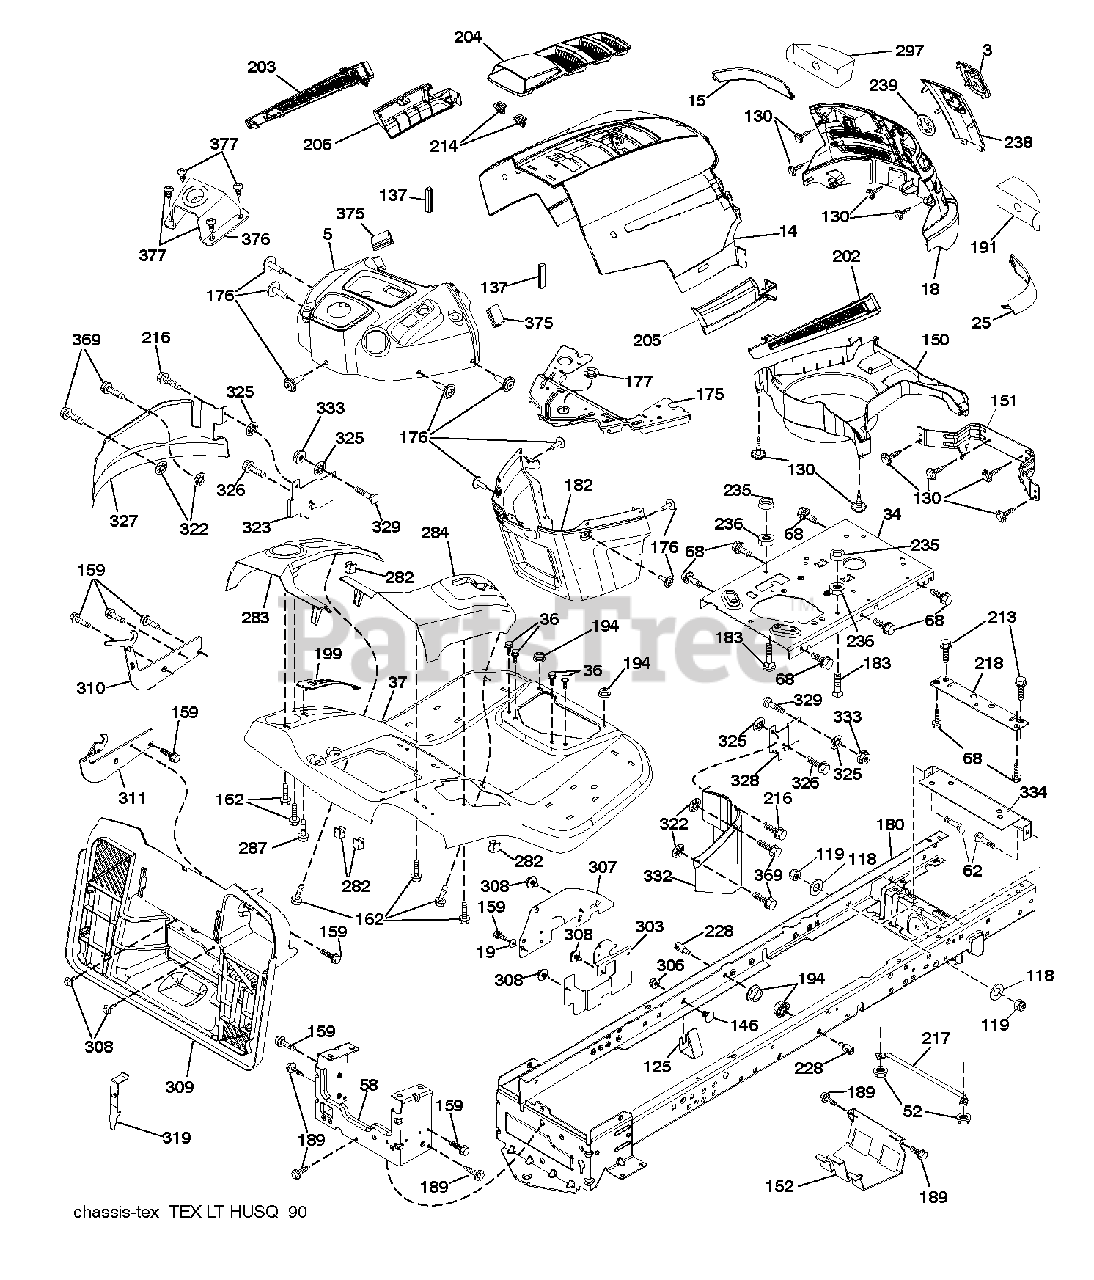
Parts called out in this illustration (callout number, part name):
3	LOGO.HUSQ.GT.LT.CROWN.H
5	DASH.UPPER.HUSQ LT CABLE.CLUTC
14	HOOD.HUSQVARNA.LT.ORANGE
15	LENS.HUSQVARNA LT.RH
18	GRILLE.SVC.HUSQVARNA.GREY
19	WASHER
25	LENS.HUSQVARNA LT.RH
34	PLATE.ENGINE.10GA.CRD.GENII
36	SCREW 5/16"
52	LOCKNUT
58	DRAWBAR UPPER 2PC SMALL FENDER
62	BOLT D
68	SCREW LT
118	WASHER
125	CLIP.FUEL.LINE
130	SCREW.#10 X 0.750.BOS
137	BUMPER DASH
146	BOLT.RDHD.SHT.SQNK.3/8-16X5/8
151	BRACKET PIVOT
152	SHIELD.BROWNING.W/TEX
159	SCREW, 3/8-16X3/4
162	SCREW.HI-LO.CONSOLE
175	CROSSMEMBER
176	SCREW.#10-24X5/8.RN.QU
177	BUSHING STEERING
180	CHASSIS.WLDMNT.14GA.2PC.18".TI
182	DASH.LOWER.PREDATOR LT
183	BOLT.5/16-18X1-1/4 FULL THD
189	SCREW
191	INSERT.REFLECTIVE.RH.
194	NUT LOCK HEX FLANGE 5/16-18
199	PLATE DECK LIFT
202	VENT.SIDE.HUSQVARNA.LT.RT
203	VENT.SIDE.HUSQVARNA.LT.LFT
204	SUBASM.TOP.VENT.HUSQ.LT
205	SKIRT.SIDE.HUSQVARNA.LT.RT
206	SKIRT.SIDE.HUSQVARNA.LT.LEFT
213	BOLT
214	CLIP.RETAINER.TINNER.
216	SCREW, 5/16-18 X 1/2
217	ROD.PIVOT.HOOD
218	X-PIECE.HOOD.STOP.NON/
228	STUD.FASTNER.W/ANTI-ROTATE
235	SPACER FENDER
236	NUT.CENTERLOCK.5/16-
238	TRIM.HUSQ LT.668
282	CLIP.RETAINER.CONSOLE.LT.HUSQ
283	CONSL.DECKLIFT.LH.SRD.TEX.CRD
284	CONSL.SHFT.PEDAL.RH.SRD.TEXCRD
287	SCREW 1/4X20
297	INSERT REFLECTIVE
303	SHIELD.LWR.LH.LT.30"CRDSRD.PNT
306	NUT LOCK FLG 3/8-16 UNC
307	SHIELD.UPPER.CRD.SRD.ISO
308	BOLT, 5/16-18 X 1 3/4
309	BACKPLATE.BAGGER.V2.SRD
310	BRACKET BRACKET.LH REAR BAG HA
311	BRACKET BRACKET.RH REAR BAG HA
319	BRACKET.ACTUATOR.BAGGER.SRD
322	PALNUT 1/4
323	GUARD FRONT LEFT
325	WASHER 5/16"
326	SCREW 14-20 X 5/8
327	GUARD LEFT
328	GUARD FRONT RIGHT
329	BOLT
332	GUARD RIGHT
333	NUT.71038.31-18.HEX.NYLOCK
334	BRACKET.ENGINE
369	SCREW.#10 X 0.500
375	BUMPER CLIP-ON. DASH 1"
376	MOUNT.ASM.HUSLT.UPPER.STRNG
377	SCREW 10 X 1/2 ZN PL PHIL PAN
